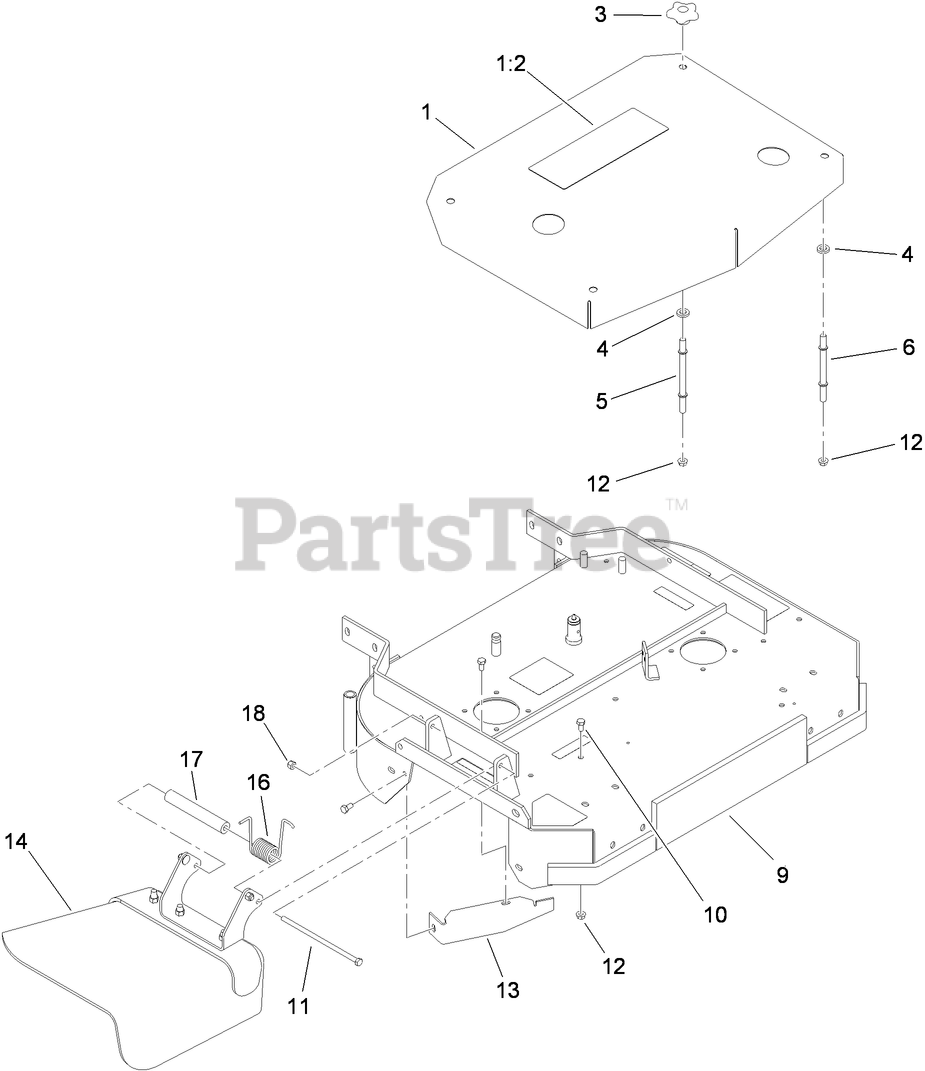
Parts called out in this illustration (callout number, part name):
1	SHIELD-BELT
3	KNOB-HANDLE
4	WASHER
5	STUD-SHIELD, BELT (LONG)
6	STUD-SHIELD, BELT (SHORT)
9	32 INCH DECK ASM
10	SCREW-HH
11	SCREW-HH
12	NUT-HF
13	BAFFLE-DOGLEG
14	DEFLECTOR ASM
16	SPRING-TORSION
17	SPACER
18	NUT-LOCK, NI
